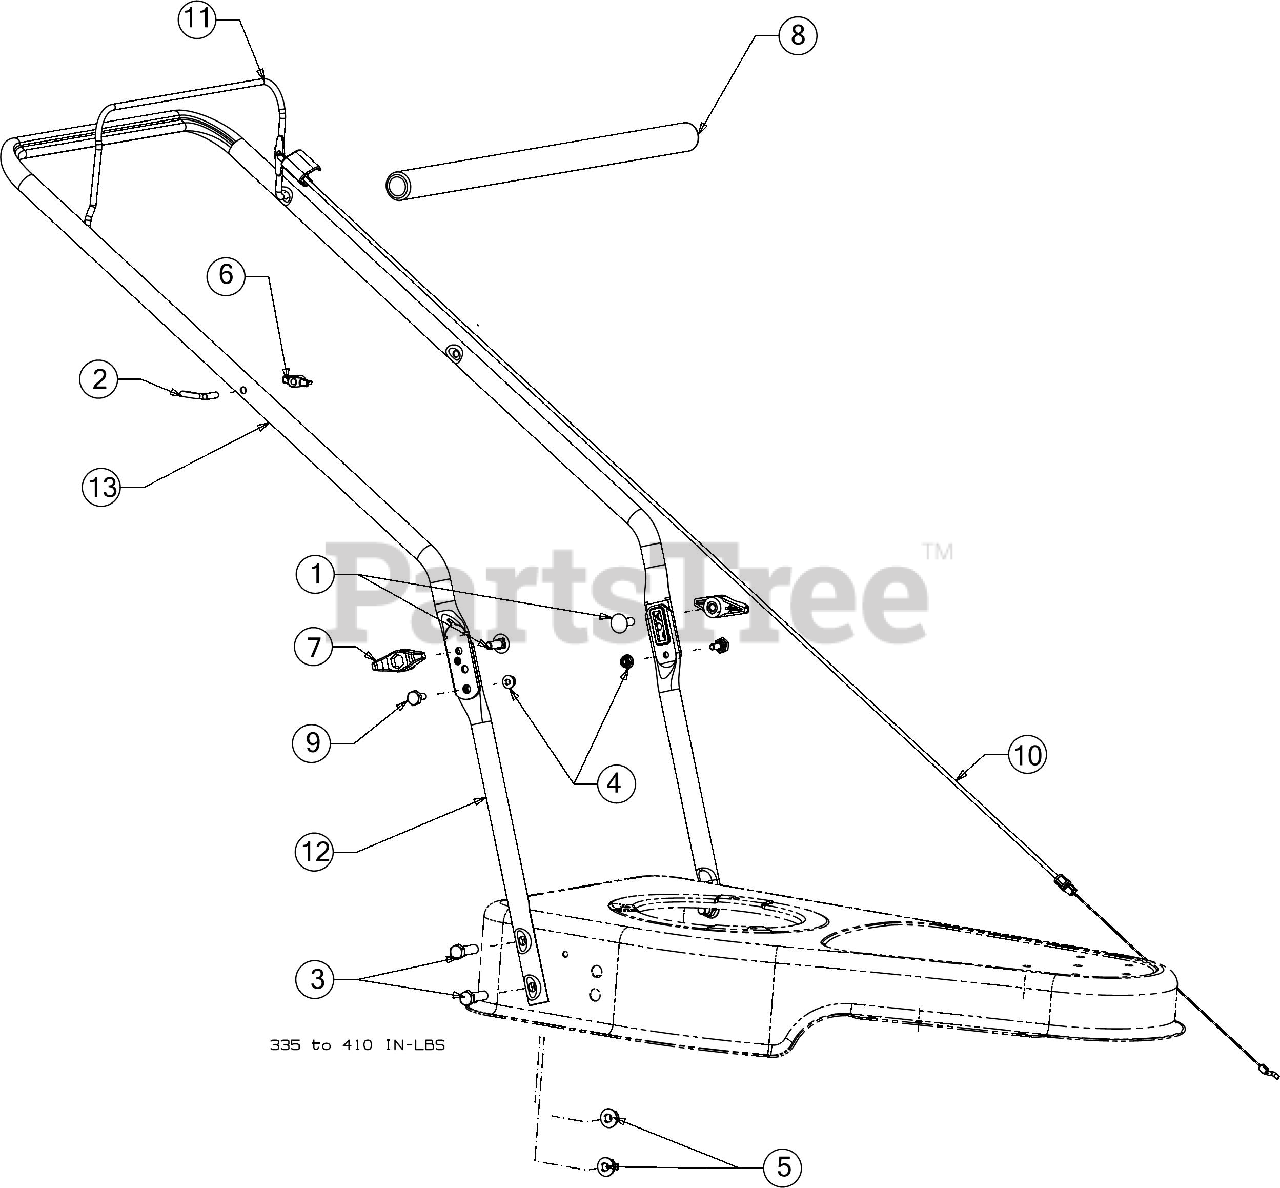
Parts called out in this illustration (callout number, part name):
1	SCREW 5/16-18 X 1.00 GR5
2	EYEBOLT 1/4-20
3	SCREW 3/8-16 X 1.25 GR5
4	FLANGE LOCK NUT
6	HANDLE KNOB
7	WING KNOB 5/16-18
8	FOAM HANDLE GRIP
9	SHOULDER SCREW
10	CONTROL CABLE 40"
11	OPERATOR BAIL
12	LOWER HANDLE (ADJUSTABLE)
13	UPPER HANDLE (ADJUSTABLE)
